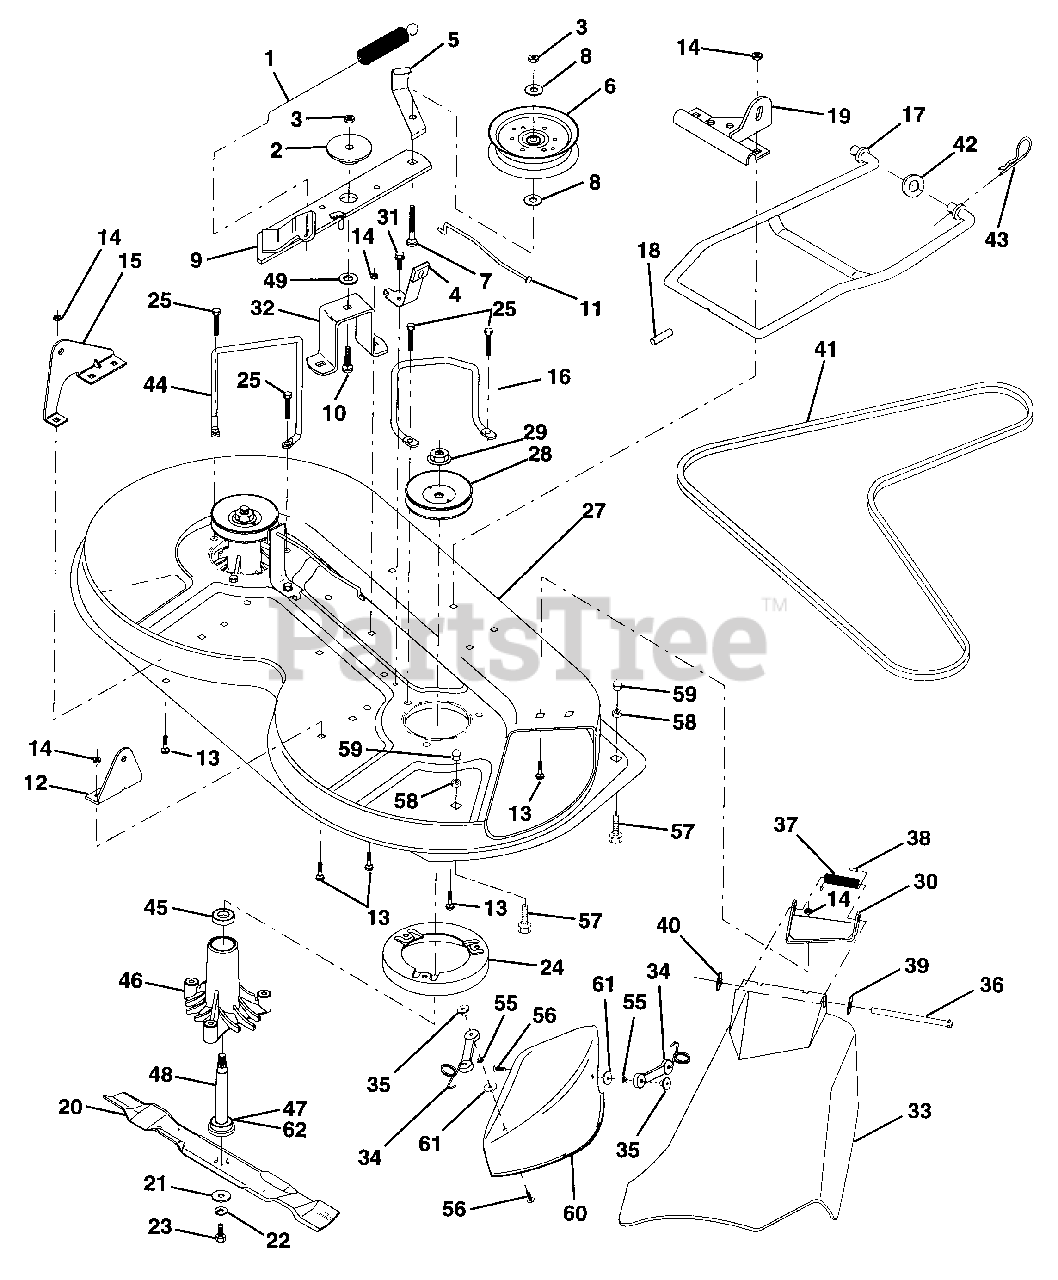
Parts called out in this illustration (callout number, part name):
1	Spring, Mower Clutch
2	Spacer, Retainer
3	Nut, Crownlock 3/8-16
4	Brake Asm.
5	Guide, Belt Idler
6	Pulley, Flat Idler
7	Bolt, Carr. 3/8-16 x 1-3/4 Gr. 5
8	Washer 13/21 x 7/8 x 10 Ga.
9	Arm Asm., Idler Mower
10	Bolt, Carriage 3/8-16 x 1-1/4
11	Rod, Brake
12	Bracket, Lift R. H. Rear
13	Bolt, Carriage 5/16-18 x 3/4
14	Nut, Crownlock 5/16-18
15	Bracket, Lift L. H. Rear
16	Keeper, R. H.
17	Link, Asm. Mower Stabilizer
18	Pin, Drive
19	Bracket, Asm. Front
20	Blade Mulching
21	Washer, Hard
22	Washer, Lock 3/8
23	Bolt 3/8-24 x 1-1/4 Gr. 8
24	Stripper
25	Screw Thdrol Hex Hd
27	Deck Assembly
28	Pulley, Mandrel
29	Nut, Flangelock 9/16
30	Bracket, Asm. Deflector
31	Screw, Hex Wsh. Thdrol. 5/16-18 x 1/2
32	Arm, Support Idler Mower
33	Deflector
34	Latch Asm, Bagger
35	Nut, Weld
36	Rod, Hinge
37	Spring, Torsion Deflector
38	Cap, Sleeve
39	Washer 11/32 x 5/8 x 16 Ga.
42	Washer 11/32 x 5/8 16 Ga.
43	Retainer, Spring
44	Keeper, L. H.
46	Housing Mandrel Vented
48	Shaft, Mandrel
49	Washer, Hardened
55	Washer, Lock
56	Screw
57	Bolt, Fin Hex 5/16-18 x 1
58	Nut, Nylon Insert
59	Nut, Acorn Hex 5/16 x 18
60	Cover, Mulching
62	Washer Felt
